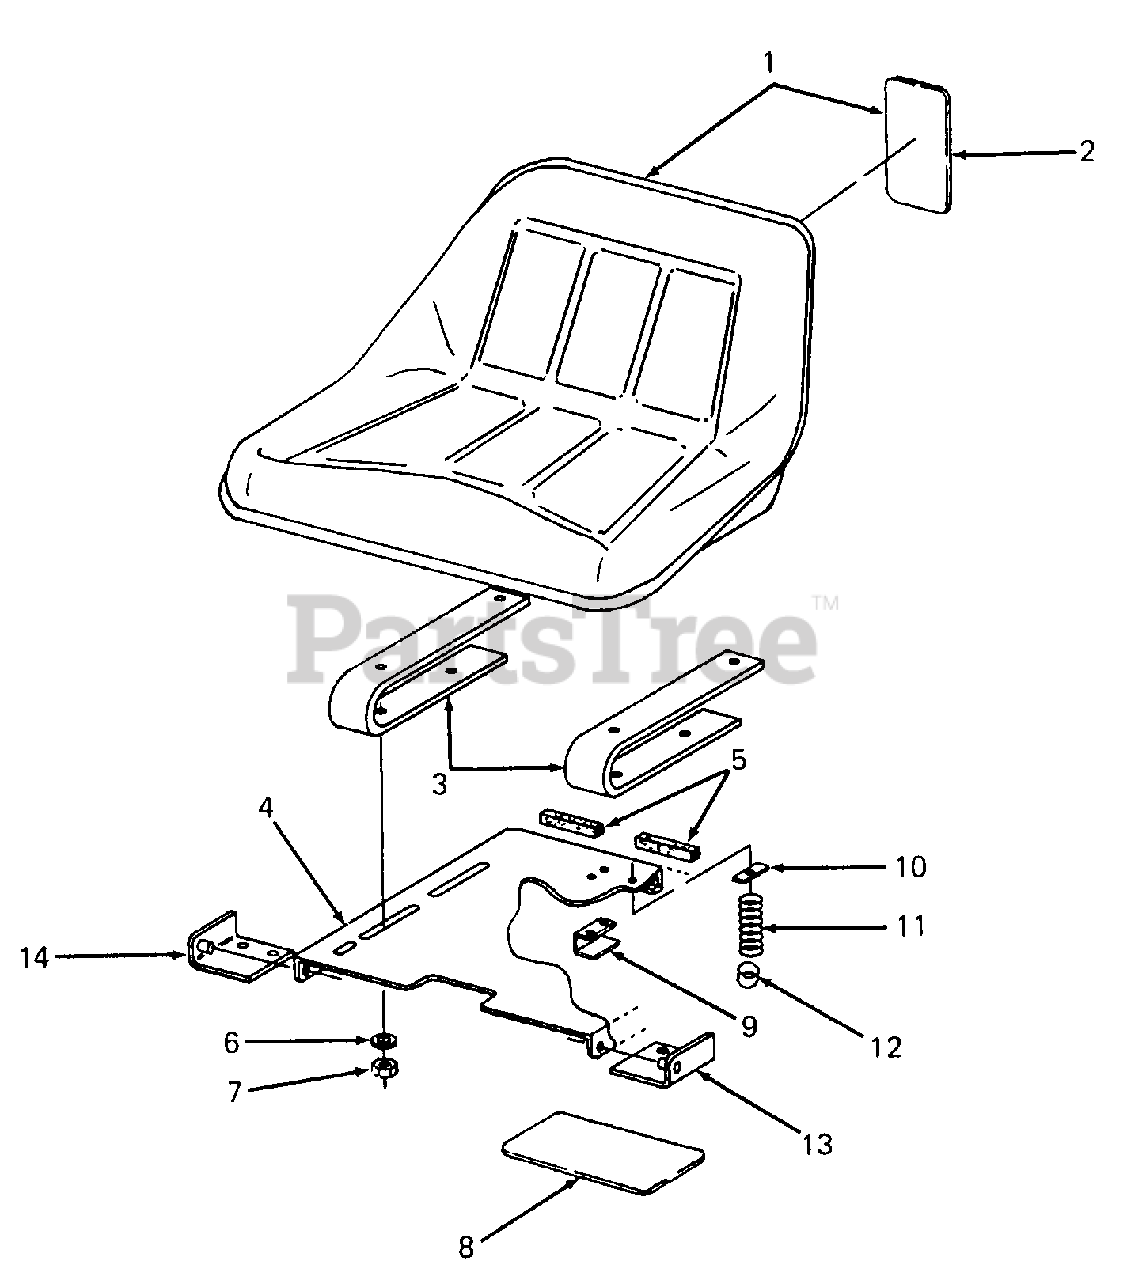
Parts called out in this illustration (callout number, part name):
1	Seat w/Graphic
2	Graphic, Caution
3	Spring, Seat
6	Washer, Bell, .345 X .88 X .06 Thk
7	Nut, Hex, 5/16-18 GR5
8	Label, Booster Battery
9	Channel, Switch Actuator
10	Nut, Spring, #10 X 1.88 Lg
11	Spring, Compression
12	Cap, Spring
